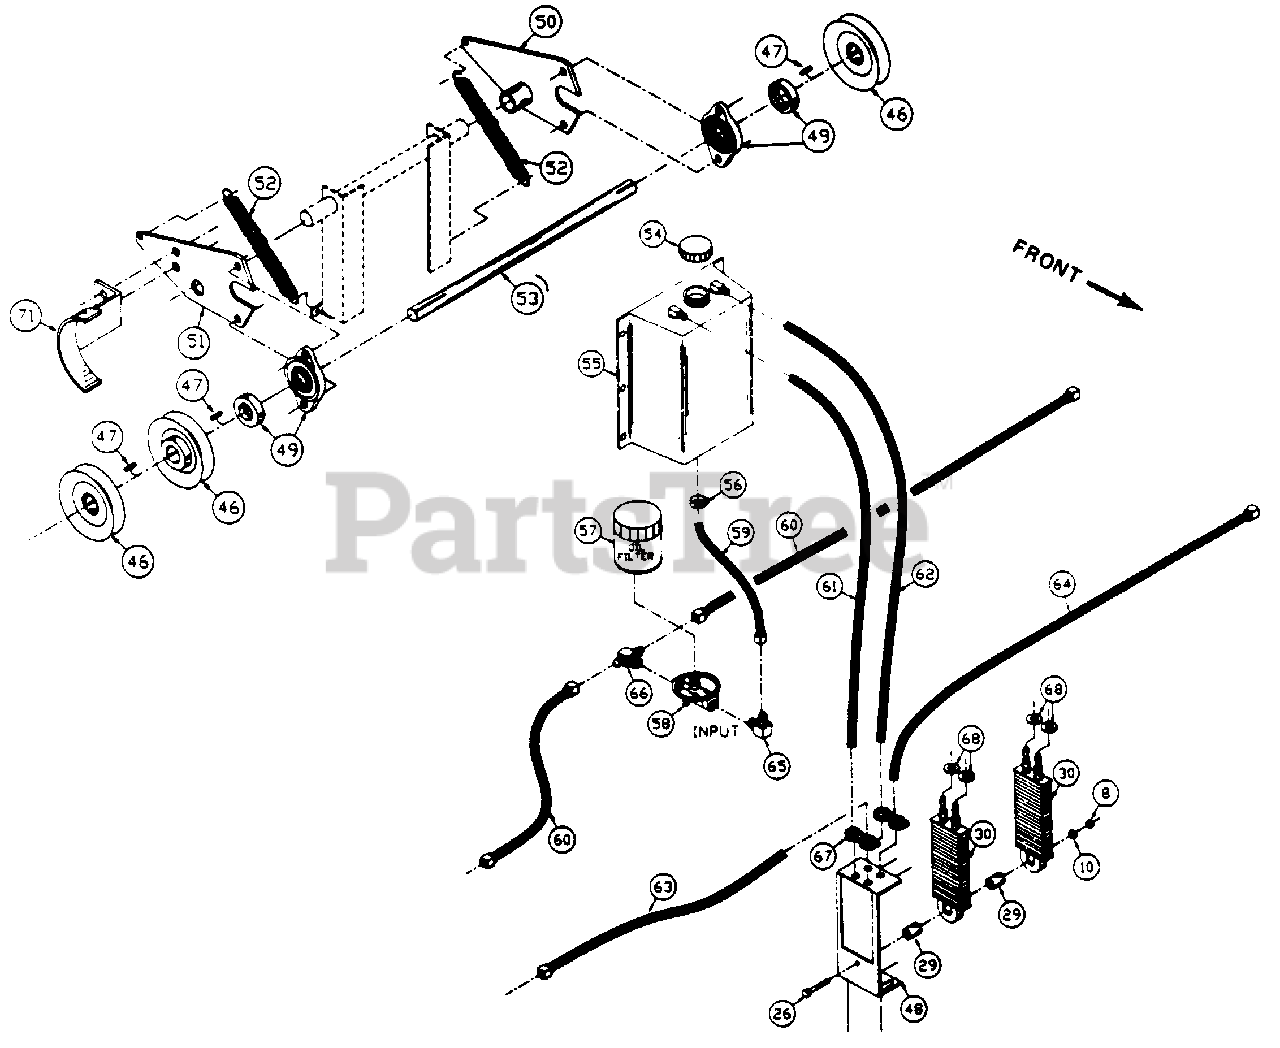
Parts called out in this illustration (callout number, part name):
8	Elastic Stop Nut, 1/4-201
10	Flatwasher, 1/4" 1
26	Hex Bolt, 1/4-20 x 2 1/4", GR5
29	Rubber Bushing
46	Pulley, 4" x 3/41 lD
47	Rey, 3/16" x 3/16' x 1"
48	Oil Cooler Mount
49	Bearing, 2-Bolt Flanged
50	Cross Shaft Bearing Mount, LH
51	Cross Shaft Bearing Mount, RH
52	Ext. Spring, l" x 71/4, 11 GA
53	Drive Cross Shaft
55	0il Tank, SA
56	Hose Clamp 5/8"
57	Filter Element
58	Filter Head, #6 Ports
59	Hose Assembly, 5/8" x 11"
60	Hose Assembly, 3/8" x 13"
61	Hose, 3/8" x 25"
62	Hose, 3/8" x 27"
63	Hose Assembly, 3/8" x 38"
64	Hose Assembly, 3/8" x 24"
65	Male Tube, 90ø Male O-ring Adpt.
66	Male O-ring, Male Tube Tee
67	Hose Clamp, 3/8"
68	Grosmet, 1/2" ID x l" OC
71	Cross Shaft Belt Retainer
